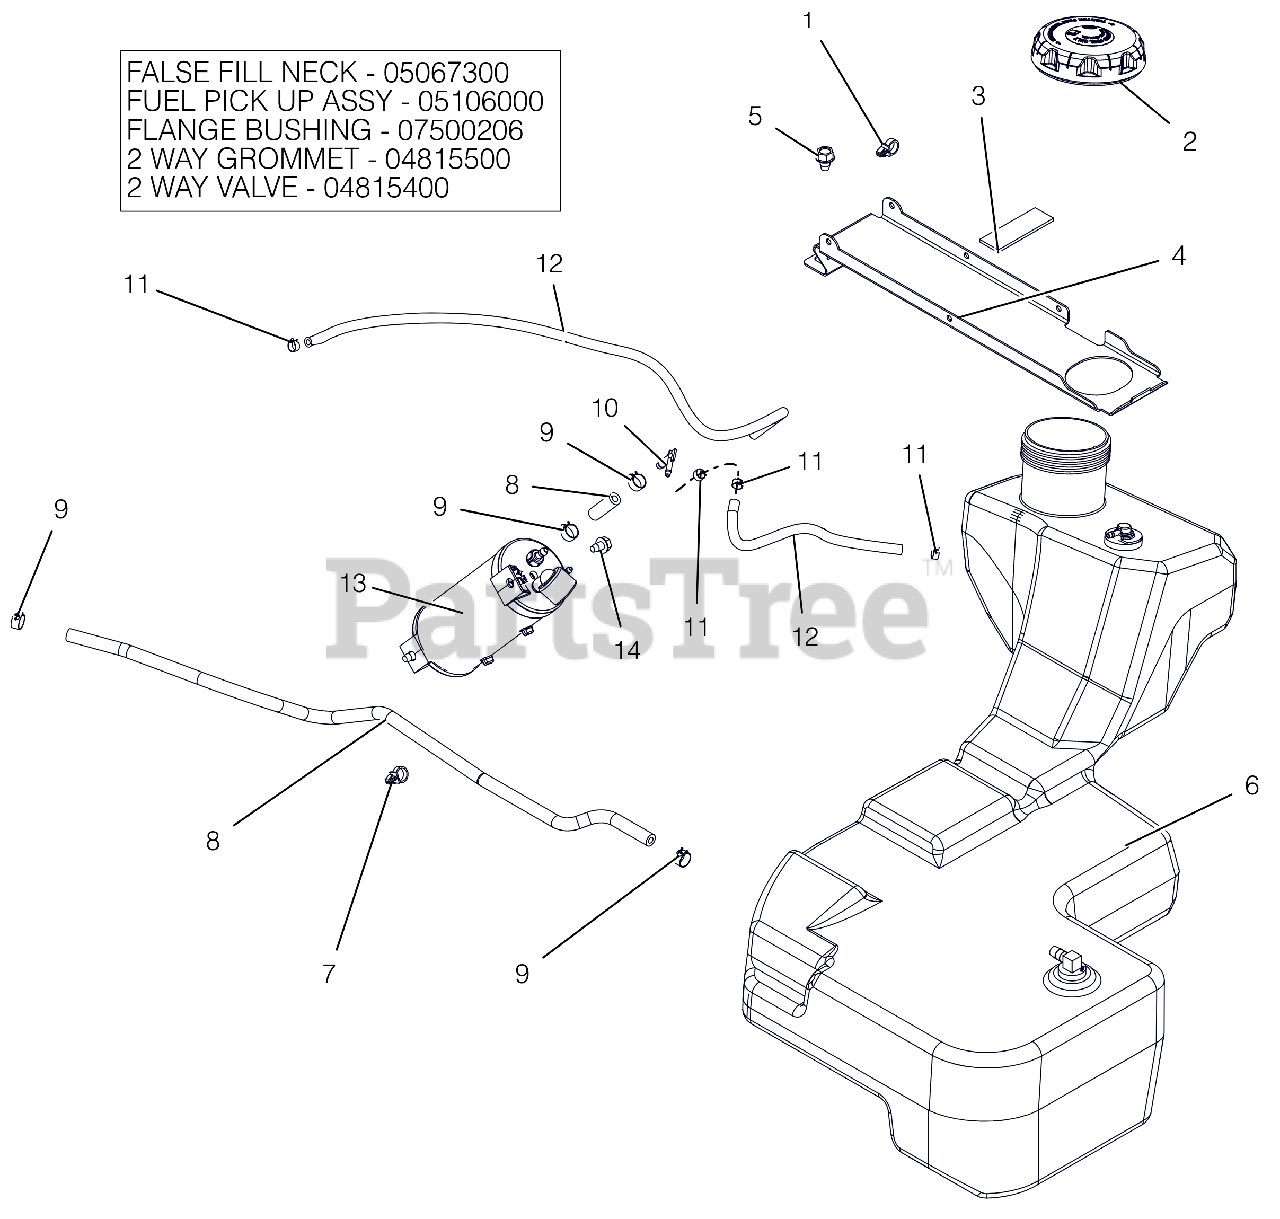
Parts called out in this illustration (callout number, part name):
1	ROUTING CLIP (1/2" ID)
2	CAP, FUEL VENTIN AUTOLOCK
3	PAD,RBR 1.0"X3.0" W/ADHESIVE
4	BRKT, FUEL TANK HOLD DOWN
5	@SCR-TAP .38-16X.50 HWH TR YWZ
6	ASM, HD FUEL TANK
6	INSERT, FUEL NECK FALSE FILL
6	ASM, HD FUEL PICK-UP
6	BSHG-FLG .375X1.062X.625 NITR
6	GROMMET, 2-WAY
6	VALVE, 2-WAY
7	ROUTING CLIP (1/2" ID)
8	HOSE, .25 LOW-PERM BULK GAS
9	CLAMP, FUEL LINE
10	FITTING-3/16X1/4 90DEGREE VAC
11	CLAMP-HOSE, SPRING .188
12	HOSE, .188 30R7 BULK
13	CANISTER, 400 CC CARB
14	@SCR-TAP .31-18X.50 HWH TR YWZ
